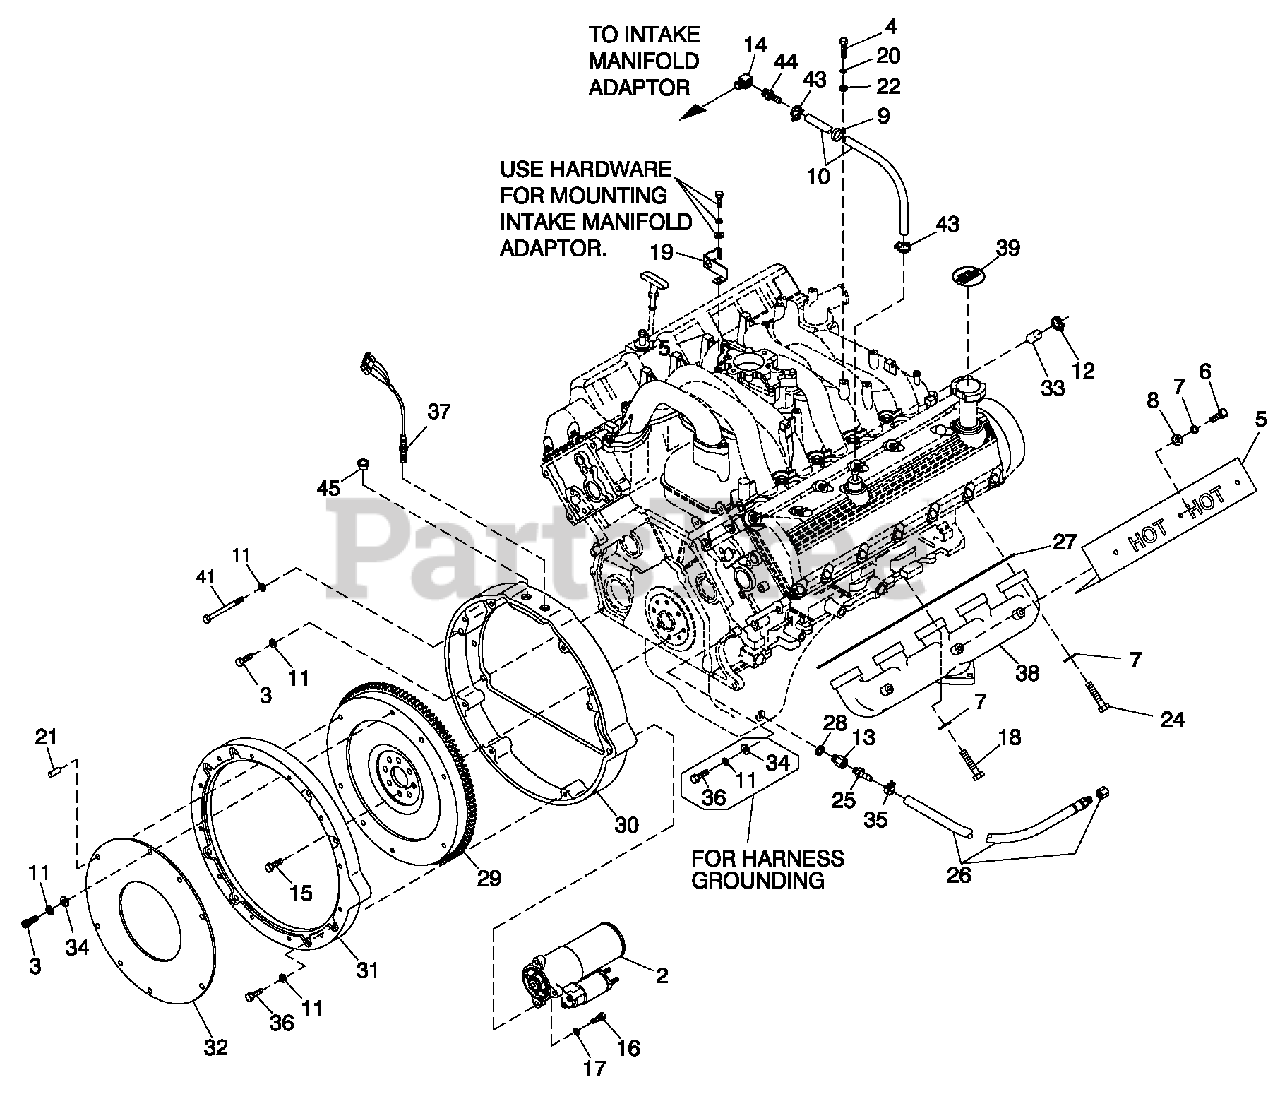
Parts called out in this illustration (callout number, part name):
2	STARTER MOTOR FORD V-10 ENGINE
3	SCREW SHC M10-1.5 X 35 G12.9
4	SCREW HHC M6-1.0X 16 G8.8
5	HEAT SHIELD EXHAUST
6	SCREW HHC 5/16-18 X 1/2 SSTL
7	WASHER LOCK M8 SSTL
8	WASHER FLAT M8 SS
9	CLAMP VINYL .75X.343Z
10	HOSE COOL 5/8" ID 250#WP (14")
11	WASHER LOCK M10
12	CLAMP HOSE #10 .56 - 1.06 (2300 & 3000RPM UNITS ONLY)
13	ADAPTER M14-1.50X 3/8 NPT
14	ELBOW 90D 1/4 NPT F-M BRASS
15	SCREW HHC M10-1.0 X 25 G10.9
16	SCREW SHC M8-1.25 X 30 G12.9
17	WASHER LOCK M8-5/16
18	SCREW HHC M8-1.25 X 35 SS F-TH
19	BRACKET SIGNAL CONDITIONER
20	WASHER LOCK M6-1/4
21	DOWEL PIN M10 X 24
22	WASHER FLAT 1/4 ZINC
24	SCREW SHC M8-1.25X35 SS
25	BARBED STR 3/8 NPT X 3/8
26	HOSE DRAIN ASSY 28"
27	GASKET EXHAUST MANIFOLD
28	WASHER NYLON .565
29	ASSEMBLY 6.8L G-BOX FLYWHEEL
30	FLYWHEEL HOUSING MACH 6.8L V10
31	COVER FLYWHEEL MACH 6.8L V-10
32	PLATE DAMPNER RETNR
33	CAP HOSE (2300 & 3000RPM UNITS ONLY)
34	WASHER FLAT 3/8-M10 ZINC
35	HOSE CLAMP BAND 5/8"
36	SCREW SHC M10-1.5 X 25 G12.9
37	ASSY MAGPICKUP(3/8-24 MALE)
38	EXH MANIFOLD MACH 6.8L V-10
39	DECAL REFER TO OWNERS MANUAL
41	SCREW SHC M10-1.50 X 100 G10.9
43	CLAMP HOSE #10 .56-1.06
44	BARBED STR 1/4 NPT X 5/8
45	PLUG PLASTIC 3/8 NPT
